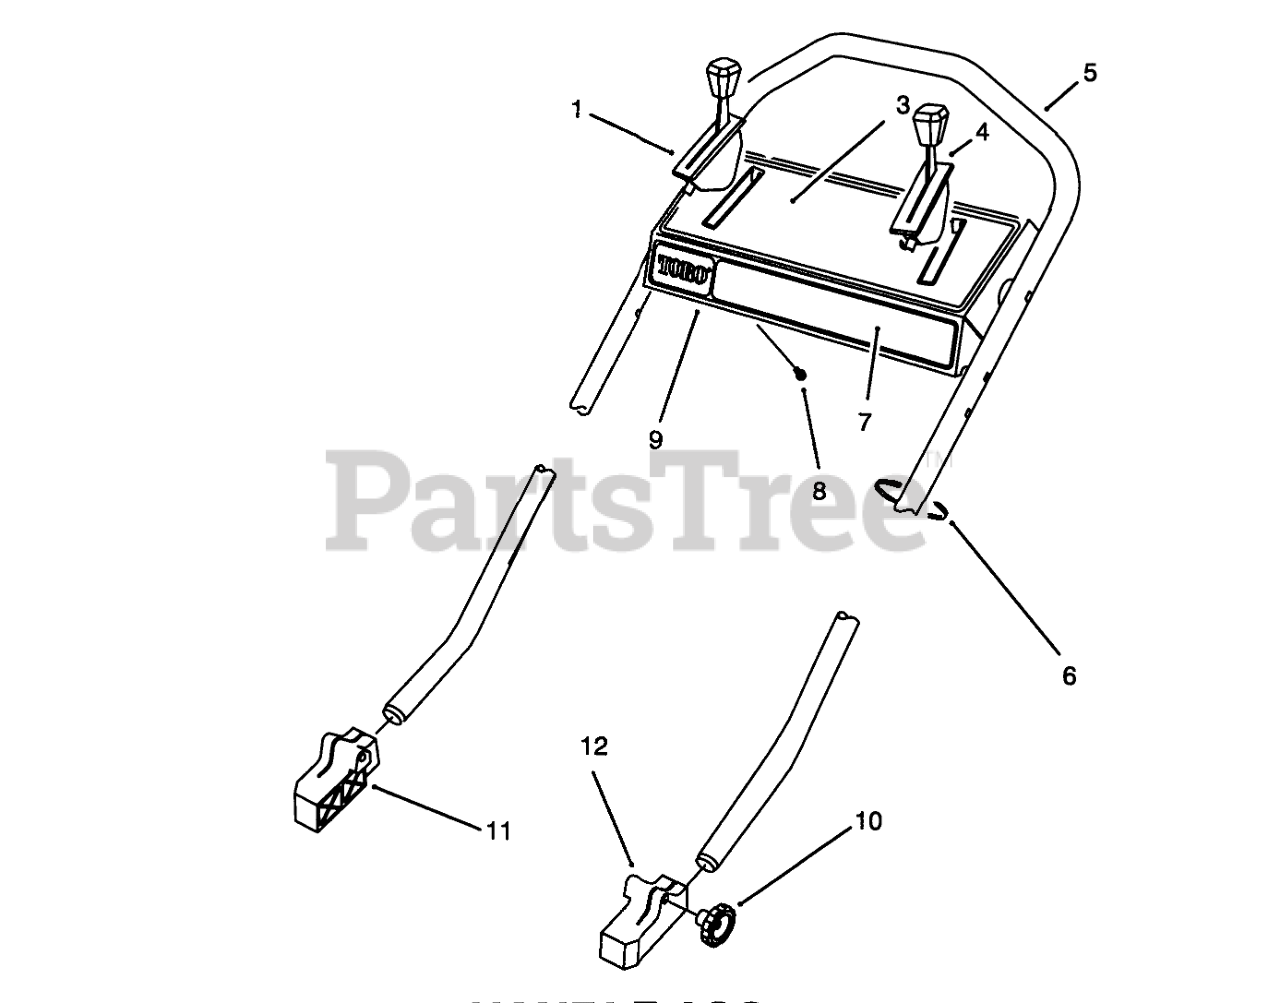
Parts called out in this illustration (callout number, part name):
1	Control-Ground Speed
3	DECAL-INSTRUCTION OHV
4	THROTTLE CONTROL
5	HANDLE PVC DIP
6	TIE-CABLE
7	DECAL-PANEL
8	SCREW-HWHTF
9	Control Panel Assembly (Incl Ref. #2,3,7)
11	MOUNT-HANDLE, RH
12	MOUNT-HANDLE, LH
